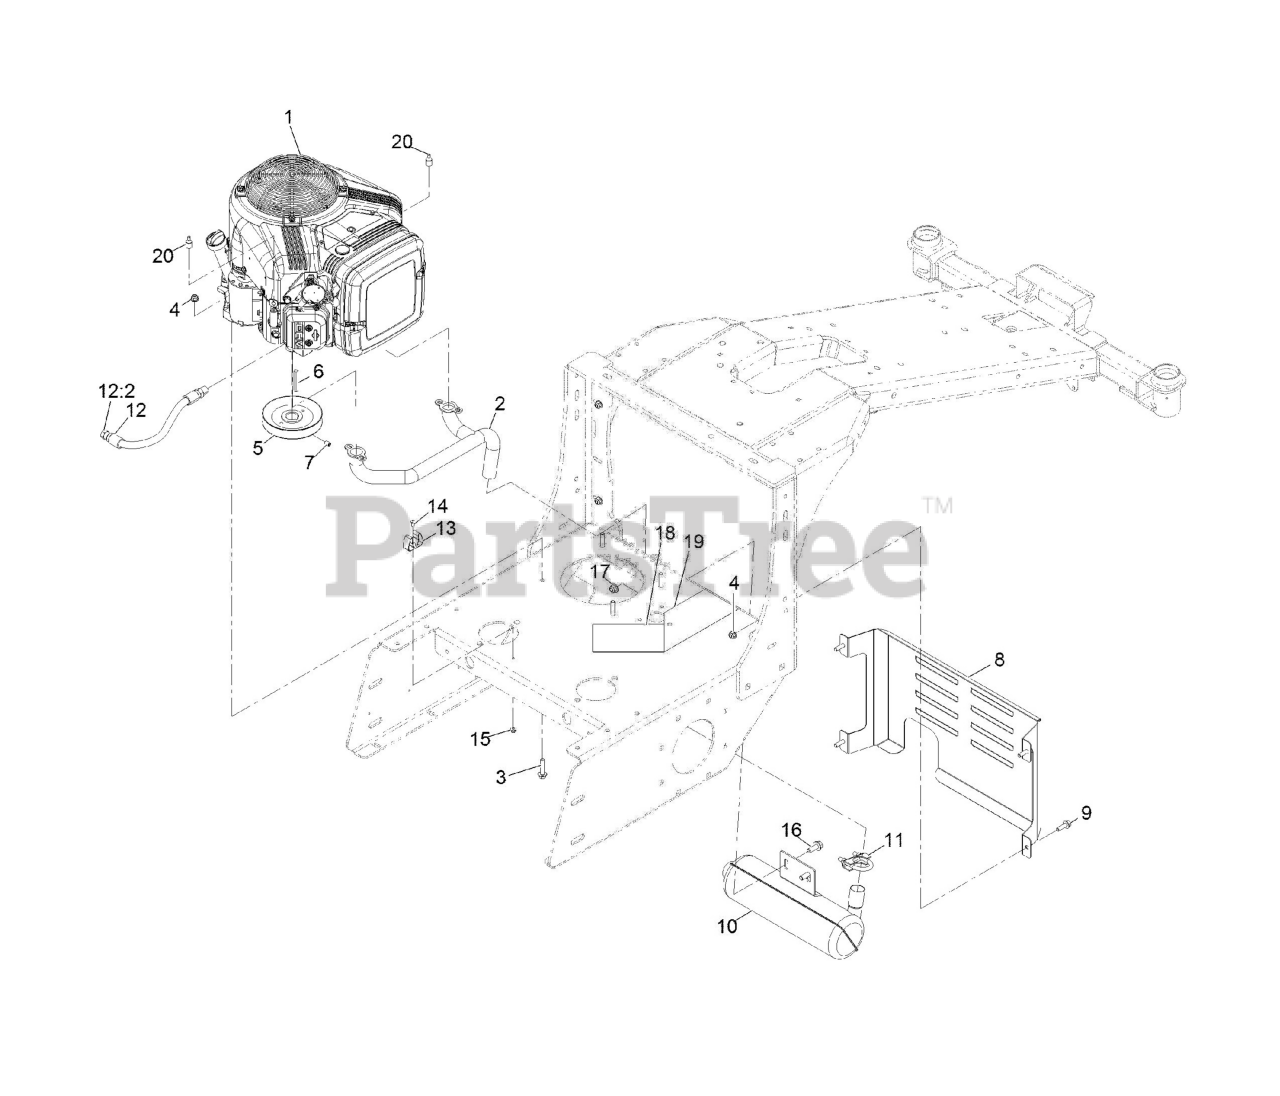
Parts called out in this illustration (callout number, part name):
1	Engine - Vanguard
2	18 HP EXHAUST MANIFOLD 4
3	SCREW-HHF
4	NUT-HF, NI
5	PULLEY-DRIVE
7	Setscrew-HSH
8	GUARD-ENGINE, AE
9	SCREW-HH
10	23HP BRIGGS MUFFLER(18HP
11	Clamp-Muffler
12	HOSE-DRAIN,3/8X15.75W/JIC
13	Holder-Tool, Clip
14	Screw-HSBH
15	Nut-Hex Flange
16	SCREW-HHF 3/8-16 X 1
17	NUT-HF, NI
18	ADHESIVE BACK, HEAT BARRI
19	TAPE-HEAT
20	Tube-Heat Shrink, 1/2
